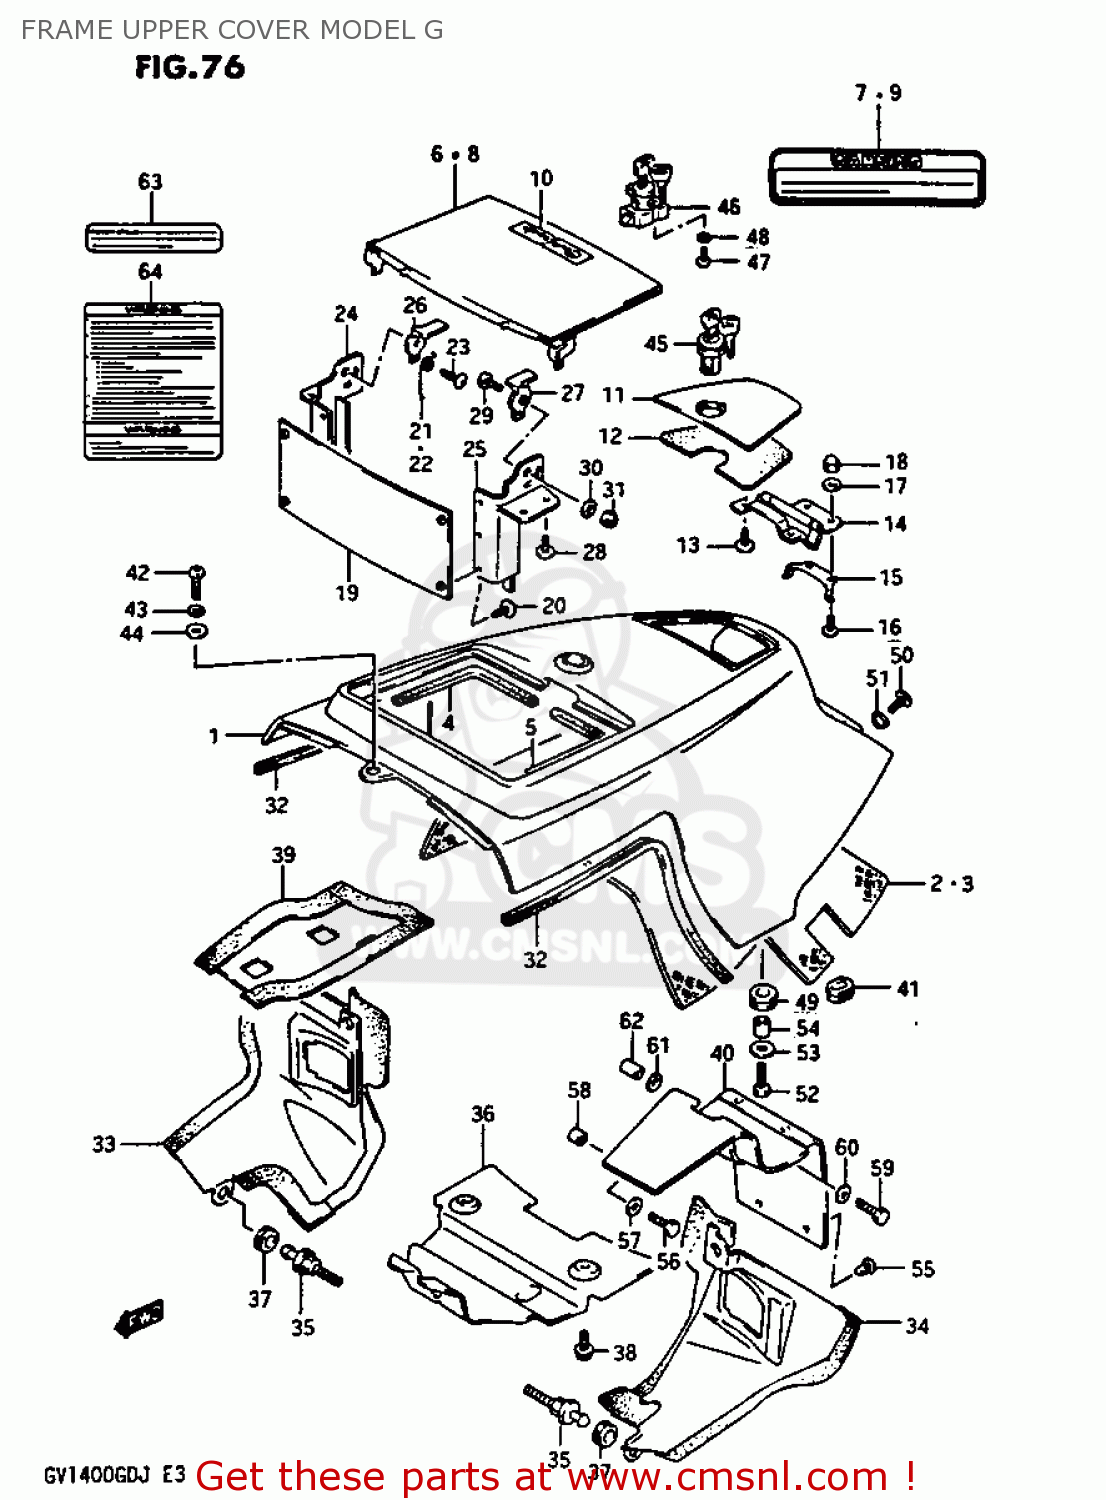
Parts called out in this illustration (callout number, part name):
1	COVER ASSEMBLY,FRAME,UPPER
2	CUSHION,FRAME COVER,UPPER
3	CUSHION,FRAME COVER,UPPER
4	CUSHION,AUDIO LID SIDE
5	CUSHION,AUDIO LID SIDE
6	LID SET,AUDIO
7	LABEL (WARNING AUDIO LI
8	LID SET,AUDIO
9	LABEL
10	EMBLEM,AUDIO LID
11	LID,FUEL
12	CUSHION,FUEL LID (NA)
13	SCREW 5X8
14	HINGE,FUEL LID
15	SPRING,FUEL LID HINGE
16	SCREW
17	WASHER
18	NUT
19	HOLDER,AUDIO LID
20	SCREW
21	SPRING
22	SPRING
23	SCREW
24	RAIL,RIGHT
25	RAIL,LEFT
26	RAIL PIECE,RIGHT
27	RAIL PIECE,LEFT
28	SCREW, RAIL
29	SCREW
30	WASHER
31	NUT 8MM
32	MOLDING,COVER FRAME,UPPER
33	COVER,INNER,RIGHT
34	COVER,INNER,LEFT
35	BOSS,FRAME COVER
36	COVER COMP,INNER
37	CUSHION
38	BOLT 6X12
39	COVER COMP,UPPER,RIGHT
40	COVER COMP,UPPER,LEFT
41	GROMMET
42	SCREW, 6X20
43	LOCK WASHER
44	WASHER (6.5X18X1.6)
45	LOCK SET,TOOL HOLDER
46	LOCK SET,AUDIO LID
47	SCREW
48	WASHER,LOCK
49	CUSHION
50	SCREW
51	WASHER
52	BOLT
53	WASHER
54	SPACER (6.1X8X9.5)
55	RIVET
56	BOLT
57	WASHER(6.5X16X1.2)
58	SPACER (6.5X12X8)
59	BOLT
60	WASHER
61	WASHER (6.3X14X1.6)
62	SPACER (6.8X10X20)
63	LABEL (WARNING AUDIO BO
64	LABEL (WARNING)
